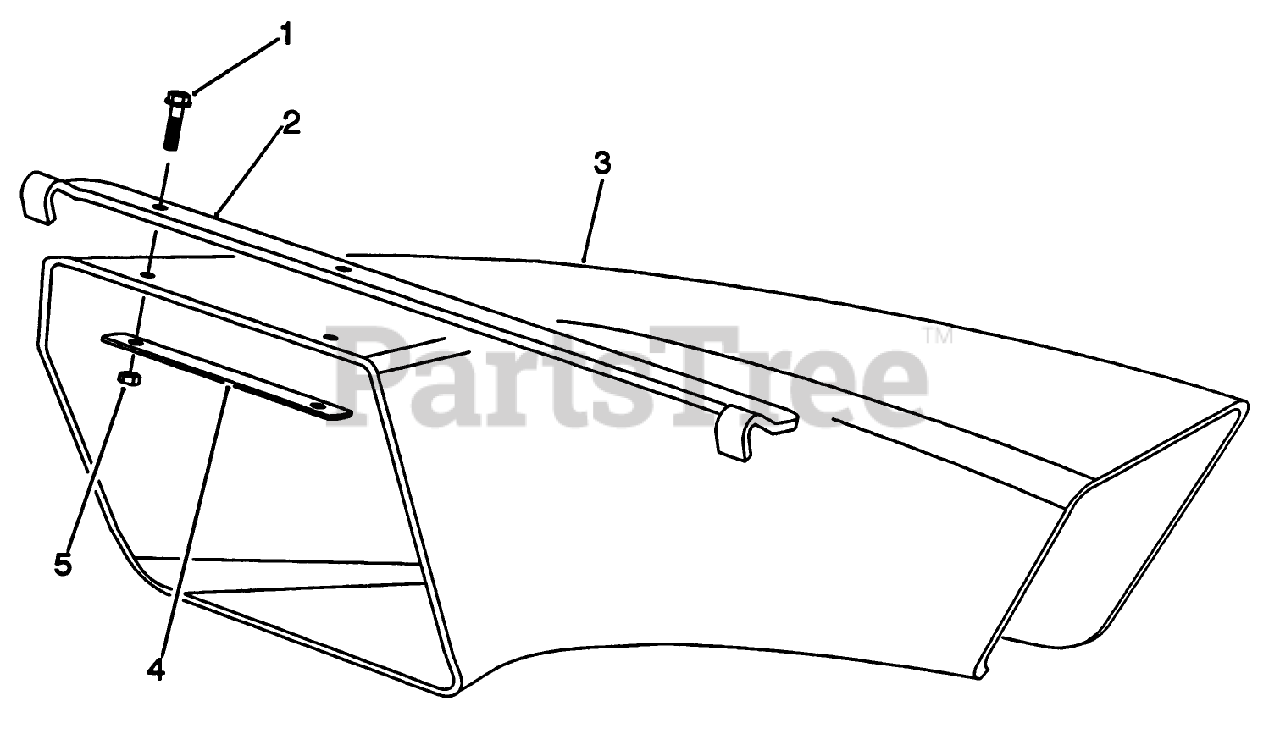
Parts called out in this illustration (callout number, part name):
1	SCREW-HWH
2	CHUTE HANGER BRACKET
3	Chute-Discharge
4	NUT-LOCK, NI
5	STRESS PLATE
